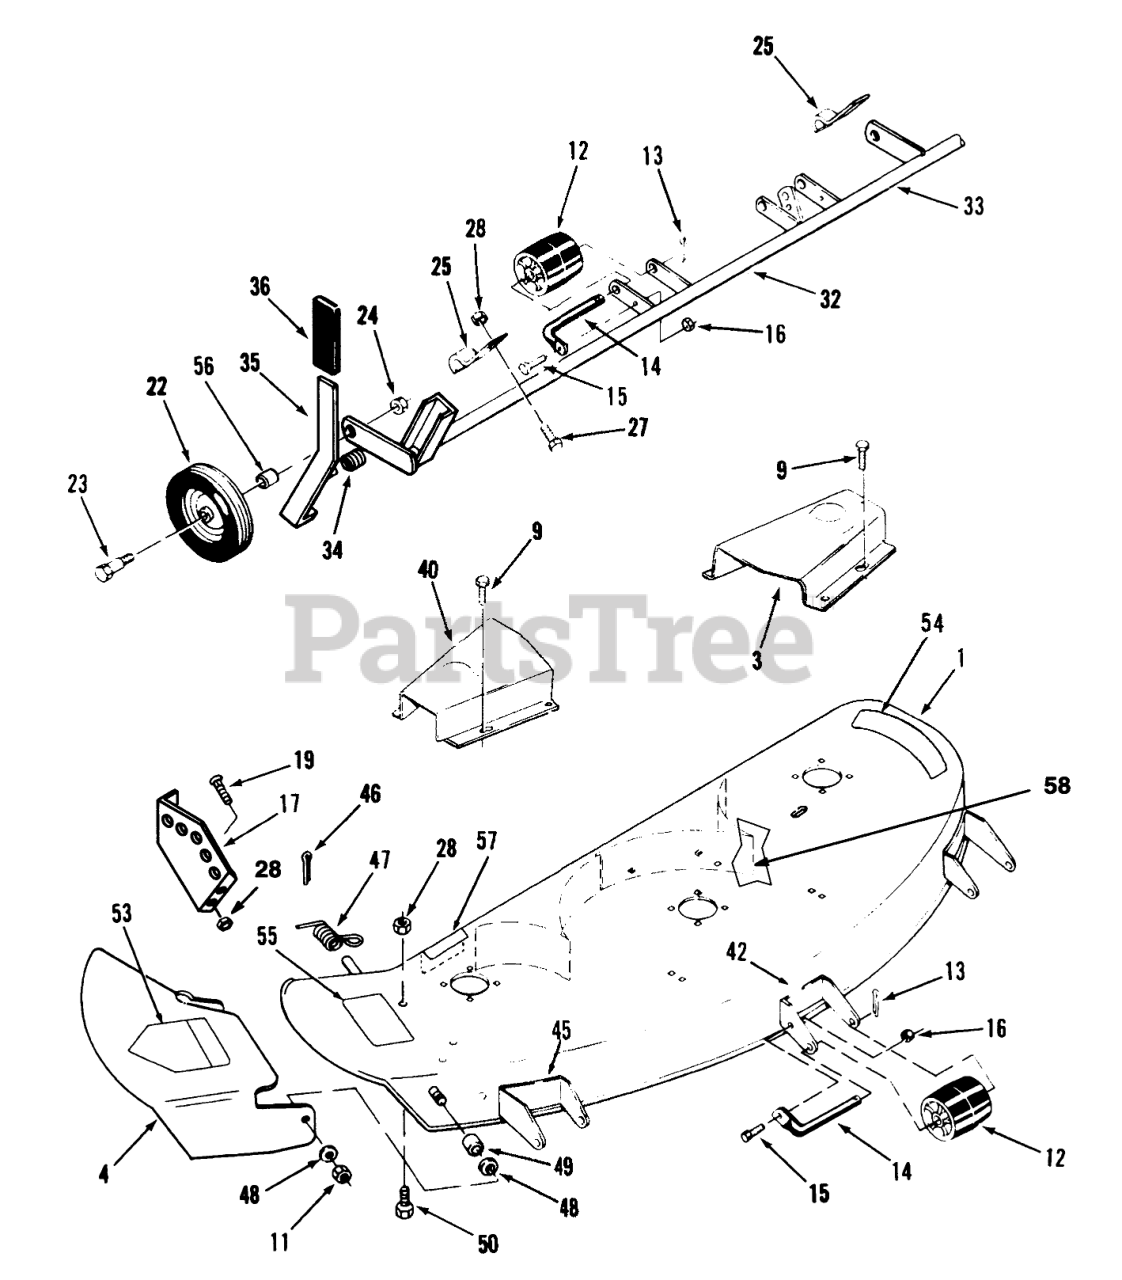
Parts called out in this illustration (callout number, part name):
1	Deck-Mower (Incl. Ref. #54 & 55)
3	Belt Cover LH
4	Extension-Chute (Incl. Ref. #53)
9	SCREW-HWH
11	NUT-JAM
12	ROLLER ASSY
13	PIN-COTTER
14	ROLLER-SHAFT
15	SCREW-HH
16	NUT-LOCK, NI
17	Quadrant
19	BOLT-CARR
22	WHEEL ASM
23	BOLT-SHOULDER
24	NUT-HEX
25	Clamp
27	BOLT-CARR
28	NUT-LOCK, NI
33	Support-Gage Wheel
34	SPRING-COMPRESSION
35	Lever
40	Belt Cover RH
46	PIN-COTTER
47	Spring
48	Washer
49	BUSHING-PIVOT
53	DECAL-DANGER
54	DECAL - DANGER
55	DECAL-DANGER, THROWN OBJECT
56	WASHER
57	DECAL-HEIGHT & BELT
58	BAFFLE-DECK R.H.
